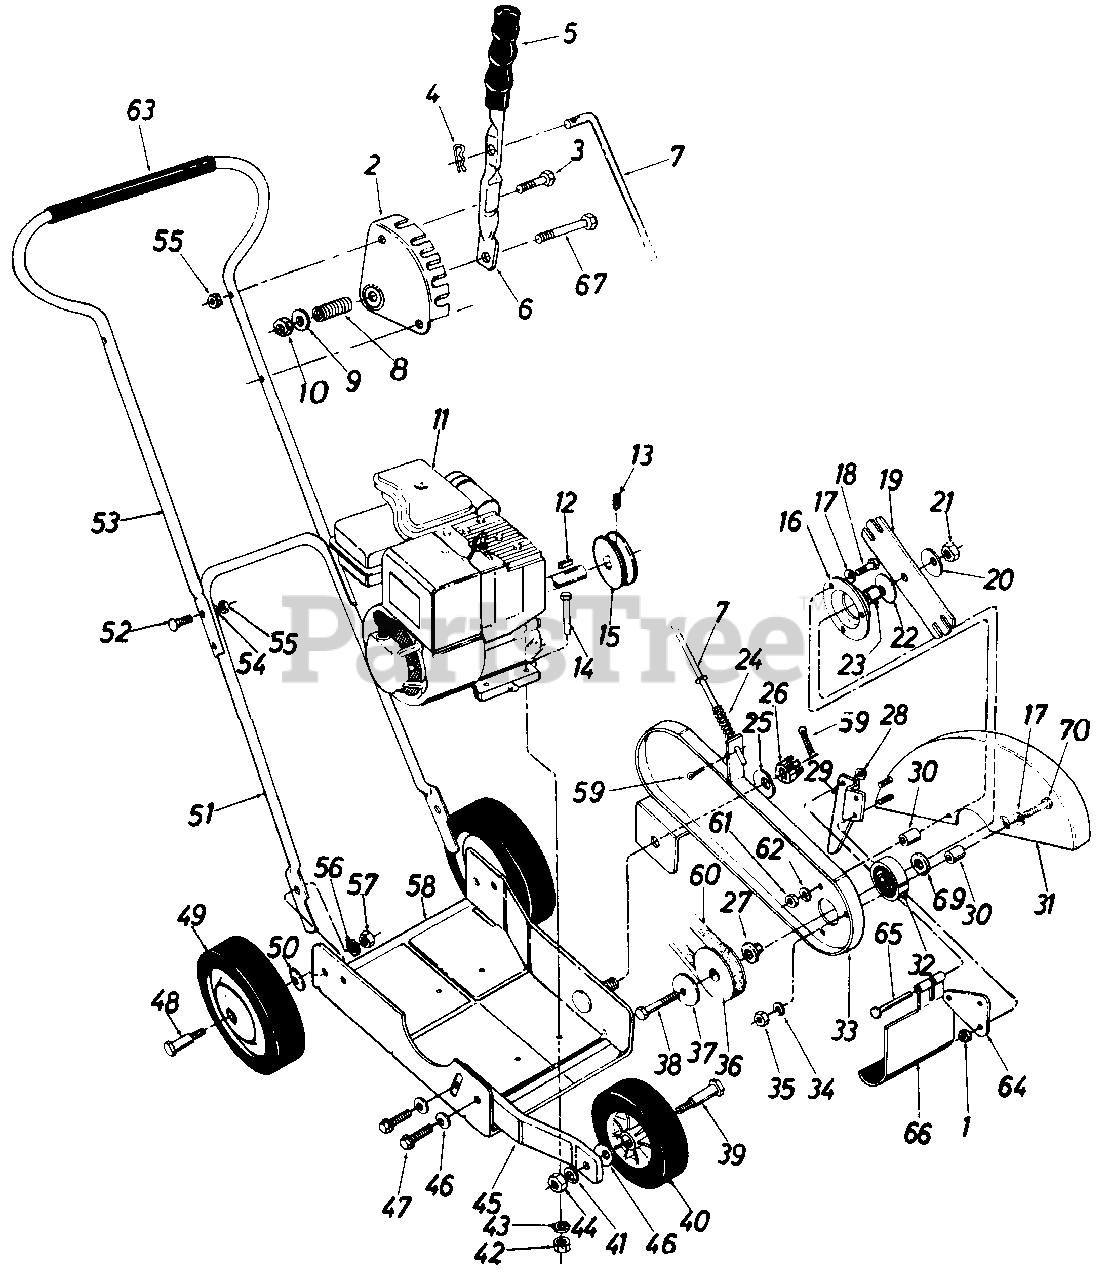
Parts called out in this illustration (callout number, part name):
1	Hex Cent. L.-Nut 1/4-20 Thd.
3	Hex Bolt 1/4-20 x 1.25" Lg.
4	Cotter Pin 1/8" Dia. x 1.0" Lg.*
8	Compression Spring .50" O.D. x 1.38" Lg.
9	Fl-Wash 34 I.D. x .62 I.D. x.063
10	Hex Cent. L.-Nut 5/16-18 Thd.
11	Engine
12	Sq.Key 3/16 x 1.0" Lg.
13	Set Scr. 1/4-28 x 1/4" Lg.
14	Hex Bolt 5/16-18 x 1.50' Lg.
15	Engine Pulley
16	Bearing Housing
17	Bell.-Wash. .34' I.D. x 88" O.D. x .060
18	Hex Bolt 5/16-18 x 1.25" Lg.
20	Bell.-Wash. .535" I.D. x 1.50" O.D. x.052
21	Hex Cent. L.-Nut 1/2-20 Thd.
22	Bell.-Wash. .535" I.D. x 1.50" O.D. x .052
23	Spacer
24	Compression Spring .57" O.D. x 1.92" Lg.
25	Bell.-Wash. .535" I.D. x 1.50" O.D. x .052
26	Hex Castle Nut 1/2-20 Thd.
27	Shoulder Spacer
30	Spacer.354" I.D. x.635" O.D. x .510" Lg.
33	Spindle Bracket Ass'y.
34	L.-Wash. 5/16" I.D.
35	Hex Nut 5/16-18 Thd.
36	Pulley Half
37	Bell.-Wash. .535" I.D. x 1.50" O.D. x.052
38	Hex Bolt 1/2-20 x 3.50" Lg.*
39	Shoulder Bolt .498" Dia. x 1 .450
40	Wheel Ass'y. Comp. 6" Dia. x 1.50
41	L.-Wash. 3/8" I.D.*
42	Hex Nut 5/16-18 Thd.
43	L.-Wash.5/16" I.D.*
44	Hex Nut 3/8-16 Thd.
45	Front Wheel Support
46	Bell.-Wash. .400" I.D. x 88" O.D. x.060
47	Hex Wash. Hd. Self Tap Scr. 3/8-1 6 x .75 " Lg.
48	Shoulder Bolt .498" Dia. x 1 .450
49	Wheel Ass'y. Comp. 7" Dia. x 1.50
50	Bell.-Wash. .400" I.D. x 88" O.D.
51	Lower Handle
52	Carriage Bolt 1 /4-20 x 1 .25 "
53	Upper Handle
54	L.-Wash. 1/4" I.D. *
55	Hex Nut 1/4-20 Thd.*
56	L.-Wash. 3/8" I.D.*
57	Hex Nut3/8-16 Thd.
58	Base Ass'y.
59	Cotter Pin 1/8" Dia. x 1.0" Lg. *
60	3V-Belt 31.2" Lg.
61	Hex Nut 5/16-18 Thd.
62	L.-Wash. 5/16" I.D.*
63	Grip
64	Flap Bracket
66	Debris Deflector
67	Hex Bolt 5/16-18 x 1.75" Lg.
69	Fl.-Wash. .51 I.D. x 1.00 O.D. x.060
70	Hex Bolt 5/16-18 x 2.00" Lq. *
